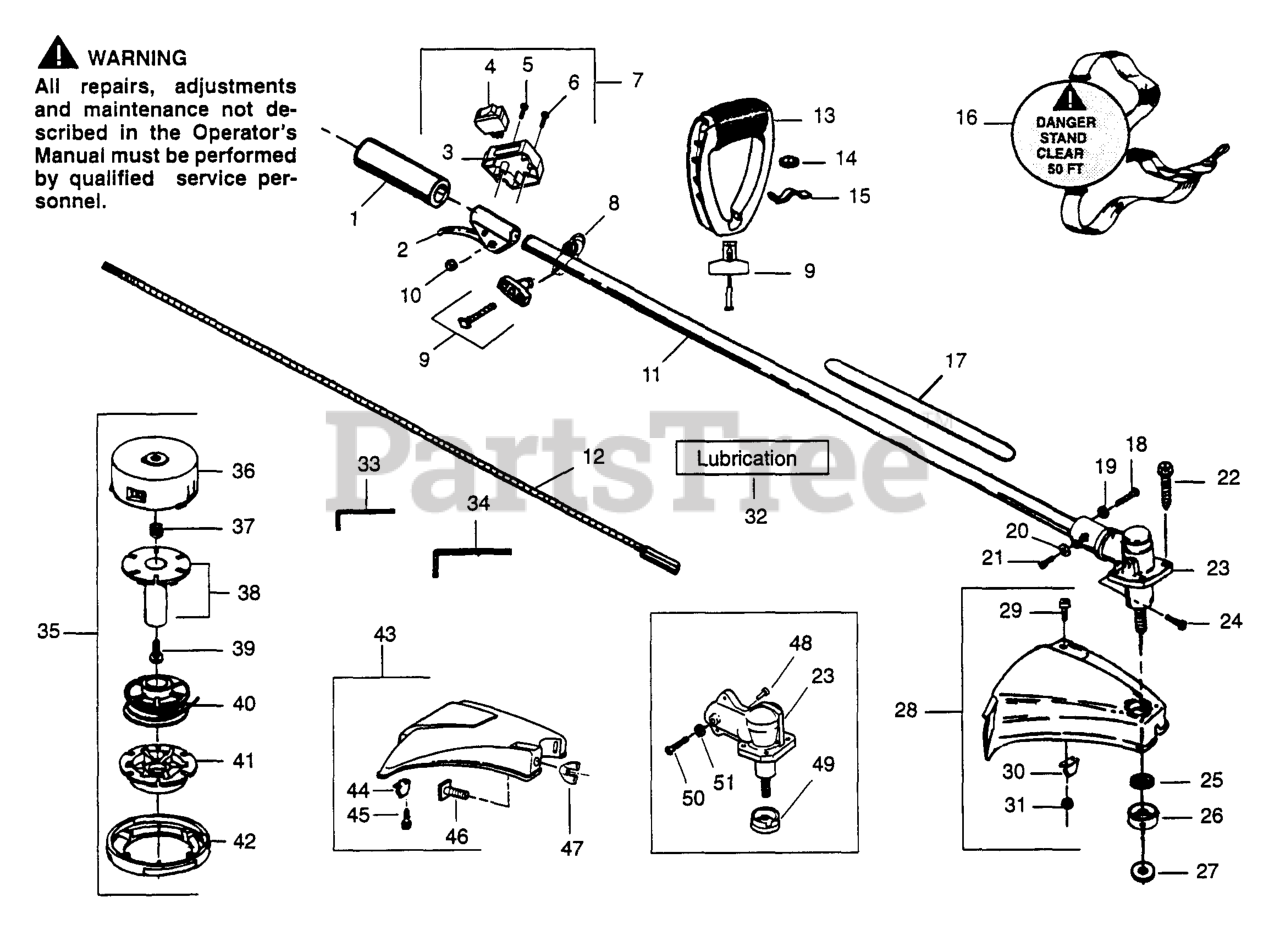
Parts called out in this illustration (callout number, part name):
2	THROTTLE HOUSING ASSEMBLY
3	COVER-KILL SWITCH (GRAY)
5	SCREW 10-24X1-5/8
6	SCREW-8-16X3/8 (PLASTIC)
7	TOP COVER SWITCH KIT
8	ASSY-CLAMP HARNESS
9	HANDLE KIT
10	LOCKNUT-HEX 10-24
11	DRIVE SHAFT HOUSING, TYPE 1
11	DRIVE SHAFT HOUSING
12	SHAFT-FLEX (53.5")
13	ASSY-HANDLE
14	NUT (1/4-20)
15	CLAMP-ASSIST HANDLE
16	STRAP-SHOULD.W/WARNING
17	Shaft Warning Decal
18	SCREW-1/4-20X1 HEX SOC
19	LOCKWASHER
20	LOCKWASHER-LOCATOR-TYPE 2
21	SCREW-10-24 X 7/16 (HEX
22	SCREW - SHIELD
23	GEAR BOX ASSY/TYPE 1
23	GEAR BOX ASS'Y, TYPE 2
27	WASHER-GRASS
28	GUARD
30	LIMITER-LINE
31	NUT 10-24 NYLOC HEX
32	GREASE 1/2 FL. OZ. TUBE
33	HEX KEY
34	HEX KEY 3/16"
35	Cutting Head Ass'y.
36	HUB ASSEMBLY
37	SPRING-COMPRESSION
38	KIT-LOCKING PLATE
40	Spool w/Line
41	Release Button
42	COVER,TRIMMY HEAD-26RLC
43	SHIELD KIT ASS'Y, TYPE 2
44	LINE LIMITER, TYPE 2
45	SCREW-10-14 X 1/2 PLASTITE
46	BOLT, TYPE 2
47	WINGNUT, TYPE 2
48	SCREW-PINCH CLAMP-TYPE 2
49	DUST CAP - TYPE 2
50	SCREW - LOCATOR - TYPE 2
51	LOCKWASHER-LOCATOR-TYPE 2
